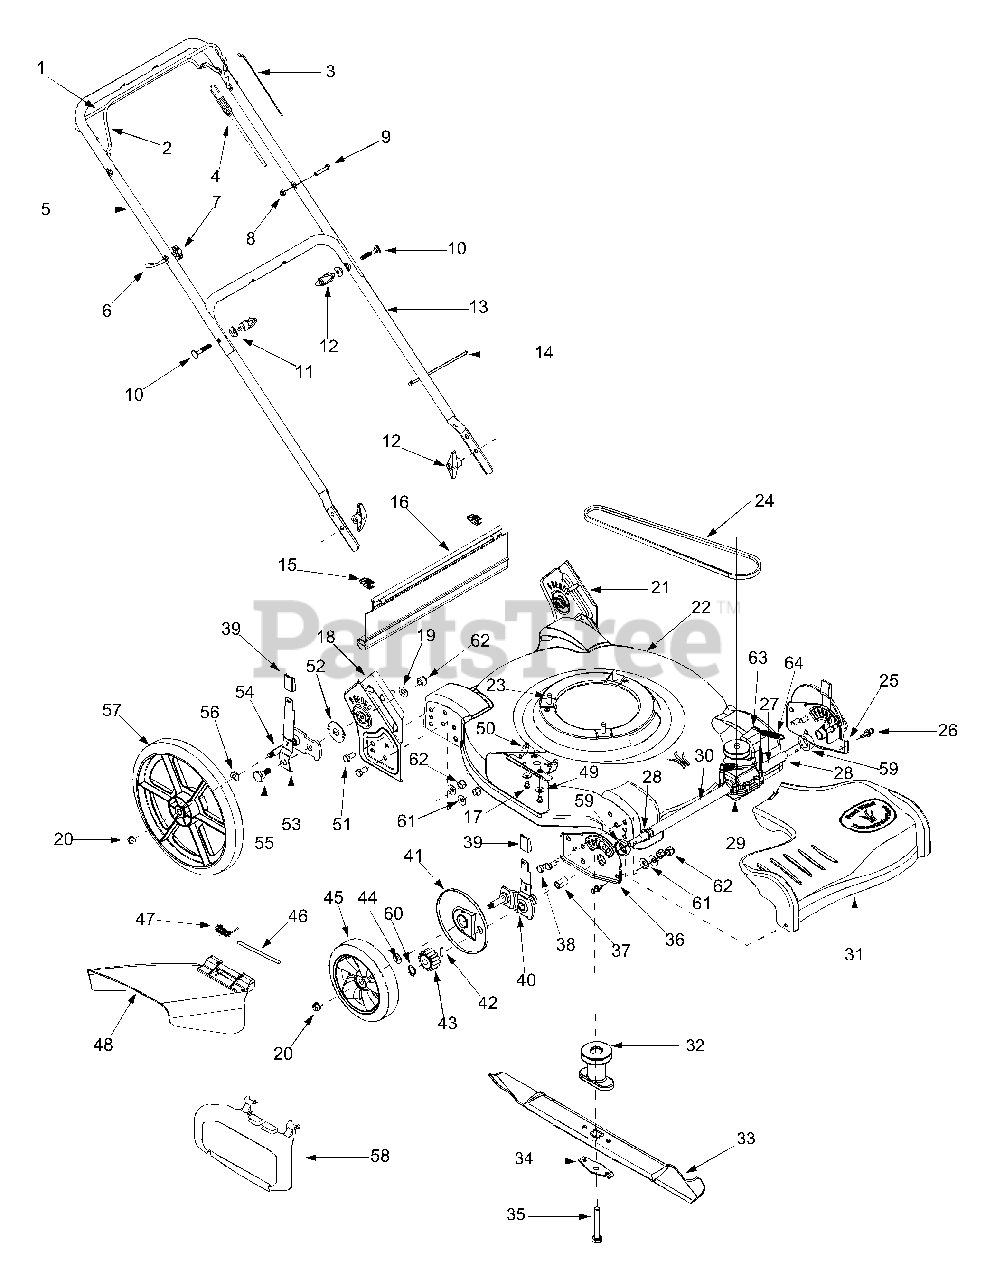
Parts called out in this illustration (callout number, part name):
1	Drive Control Handle
3	Blade Control Cable - B&S (37.75")
3	Blade Control Cable - B&S (40.75")
3	Blade Control Cable- Tec (50.5")
4	Drive Control Cable
6	Eye Bolt
7	Wing Nut 1/4-20
8	Hex Lock Nut 1/4-20
9	Hex Cap Screw 1/4-20x 1.5
10	Carriage Bolt 5/16-18 x 2.0
11	Shoulder Washer .320 ID x .93 OD
12	Wing Nut
14	Cable Tie
15	Hinge Clip
16	Trail Shield (4.5 x 17.5)
16	Trail Shield (5 x 17.5)
17	Hex Screw 1/4-14 x .625
19	Flat Washer .406 ID x .812 OD
20	Lock Nut 3/8-16
23	Hex Washer Screw 3/8-16 x 1.0
24	V-Belt
26	Rivet
27	Sleeve Spacer .550 ID x 3.3
28	Retainer Ring
29	Transmission Assembly Complete
30	Sleeve Spacer .550 ID x 7.95
31	Transmission Cover
32	Blade Adapter
33	Blade 22"
33	Mulching Blade 22"
34	Bell Washer
35	Hex Cap Screw 3/8-24 x 1.5
37	Sleeve Bearing
38	Hex Cap Screw 3/8-16 x .75
39	Adjustment Knob
40	Spring Lever Assembly - LH* (FWD)
40	Spring Lever Assembly - RH* (FWD)
41	Wheel Dust Cover
42	Pin
43	Spur Gear 14T - LH
43	Spur Gear 14T - RH
44	Flat Washer .50 x 1.00 x .030
45	Front Wheel 8 x 1.8
45	Front Wheel 8 x 2
46	Hinge Pin
47	Torsion Spring
48	Side Discharge Assembly
49	Bell Washer .265 ID x .75 OD
50	Chute Hinge
51	Hex Cap Screw 3/8-16 x .75
52	Thrust Bearing .688 ID x 1.938 OD
53	Spring Lever
54	Rear Pivot Arm Assembly
55	Shoulder Screw 3/8-16
56	Spring Washer
57	Rear Wheel 14 x 1.8
57	Rear Wheel 14 x 2
58	Snap Mulching Plug
59	Bearing Spacer
60	Snap Ring .500
61	Washer Spacer .401 ID x .870 OD
62	Hex Lock Nut 3/8-16
64	Spring .47 OD x 2.50
